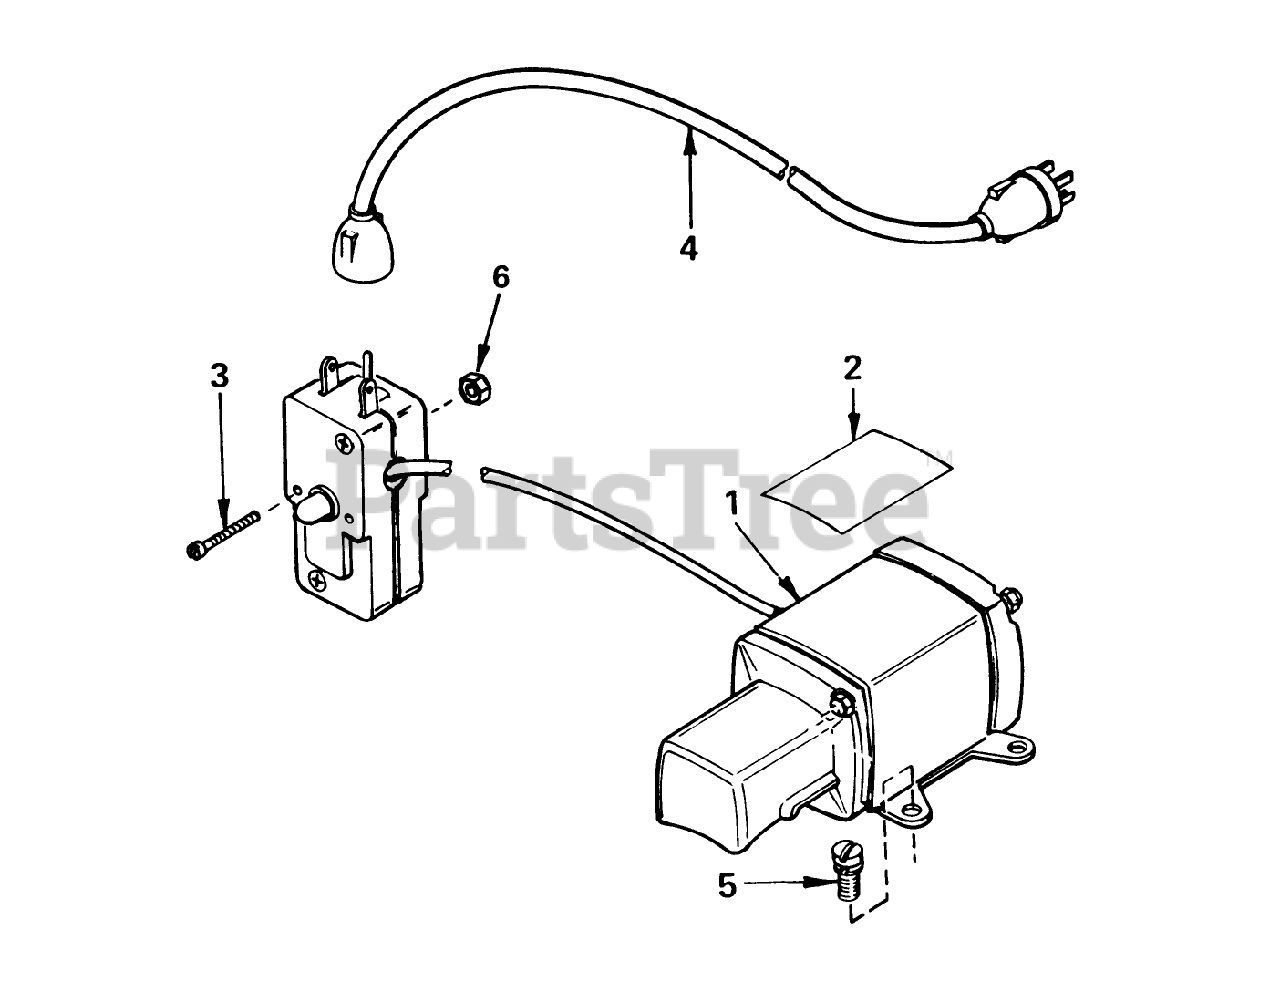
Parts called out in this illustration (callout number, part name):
1	Motor, Cranking (CSA Approved) (Incl. #2 thru 6)
2	Decal
3	Screw, Pan Hd.
4	Cord-Extension
5	Screw (T-30, 1/4-20 x 23/32)
6	Nut Lockwasher
